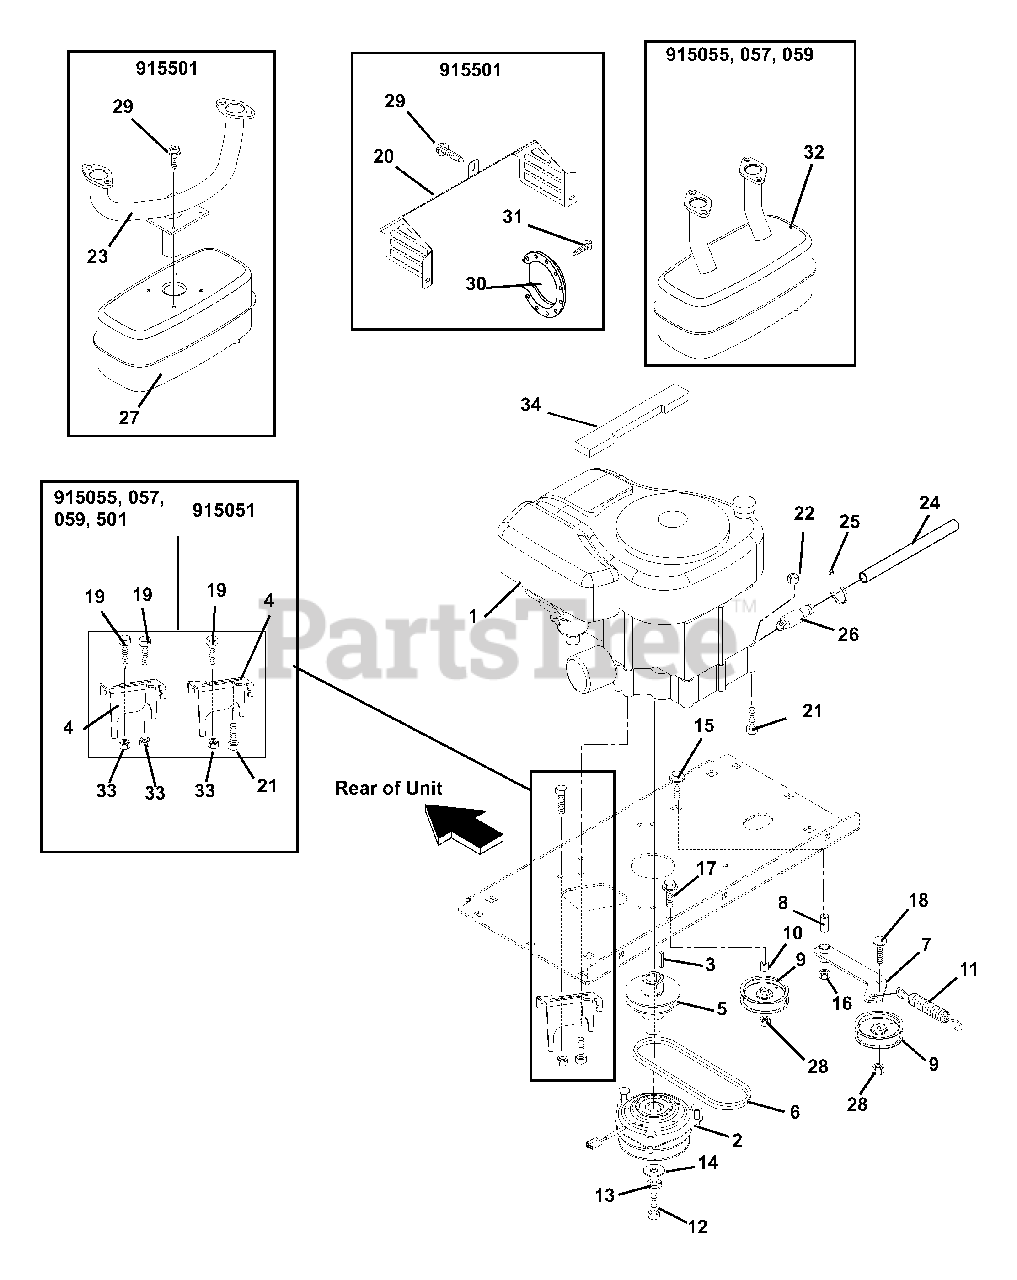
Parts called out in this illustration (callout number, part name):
1	ENGINE GROUP - 16HP
1	SERVICE ENGINE,21 HP KOHLER
1	SERVICE ENGINE,23 HP KOHLER
1	ENGINE GROUP - 18HP
1	ENGINE, 19HP KOHLER
2	CLUTCH,ELECTRIC PTO
3	KEY-SQ .25 X 1.50 X .25 SAE
4	STOP, CLUTCH
5	EXTENSION SHAFT
6	BELT,HA WRAPPED
7	WMT, IDLER
8	BSHG-SLV .500X.750X1.560
9	IDLER-FLAT 4.00 X .38 NWHAMSHR
10	BSHG,SPCR .41 X .75 X .88 PM
11	SPRING, EXT
12	BLT-HEX .44-20X4.50 GR8 YWZC
13	@WSHR-LK .44X.109 REG YWZC
14	WSHR-FL-STL .469X2.00X.25 YWZC
15	@BLT-HEX .50-13X2.50 GR5 YWZC
16	@NUT-LK-TOP-FLG .50-13 YWZC
17	@BLT-RDHDSQNK .38-16X2.00 G5YZ
18	@BLT-RDHDSQNK .38-16X1.25 G5YZ
19	@BLT-HEX .38-16X1.00 GR5 YWZC
20	MUFFLER GUARD, 40CI
21	@BLT-HEX .31-18X1.75 GR5 YWZC
22	@NUT-LK-NYL-FLG .31-18 YWZC
23	PIPE, EXHAUST
24	TUBE, OIL DRAIN
25	CABLE TIE LG 5-1/2
26	VALVE, OIL DRAIN
27	MUFFLER - EXHAUST
28	@NUT-LK-CTR-JAM .375-16 YWZC
29	@SCR-TAP .25-20X.50 HWH TR YWZ
30	DEFLECTOR B+S 222573
31	SCR-TAP 8-32X.38 SL HWH YWZC
32	MUFFLER
33	@NUT-LK-NYL-FLG .38-16 YWZC
34	FOAM SEAL, 1.5"X3.5"X24"
